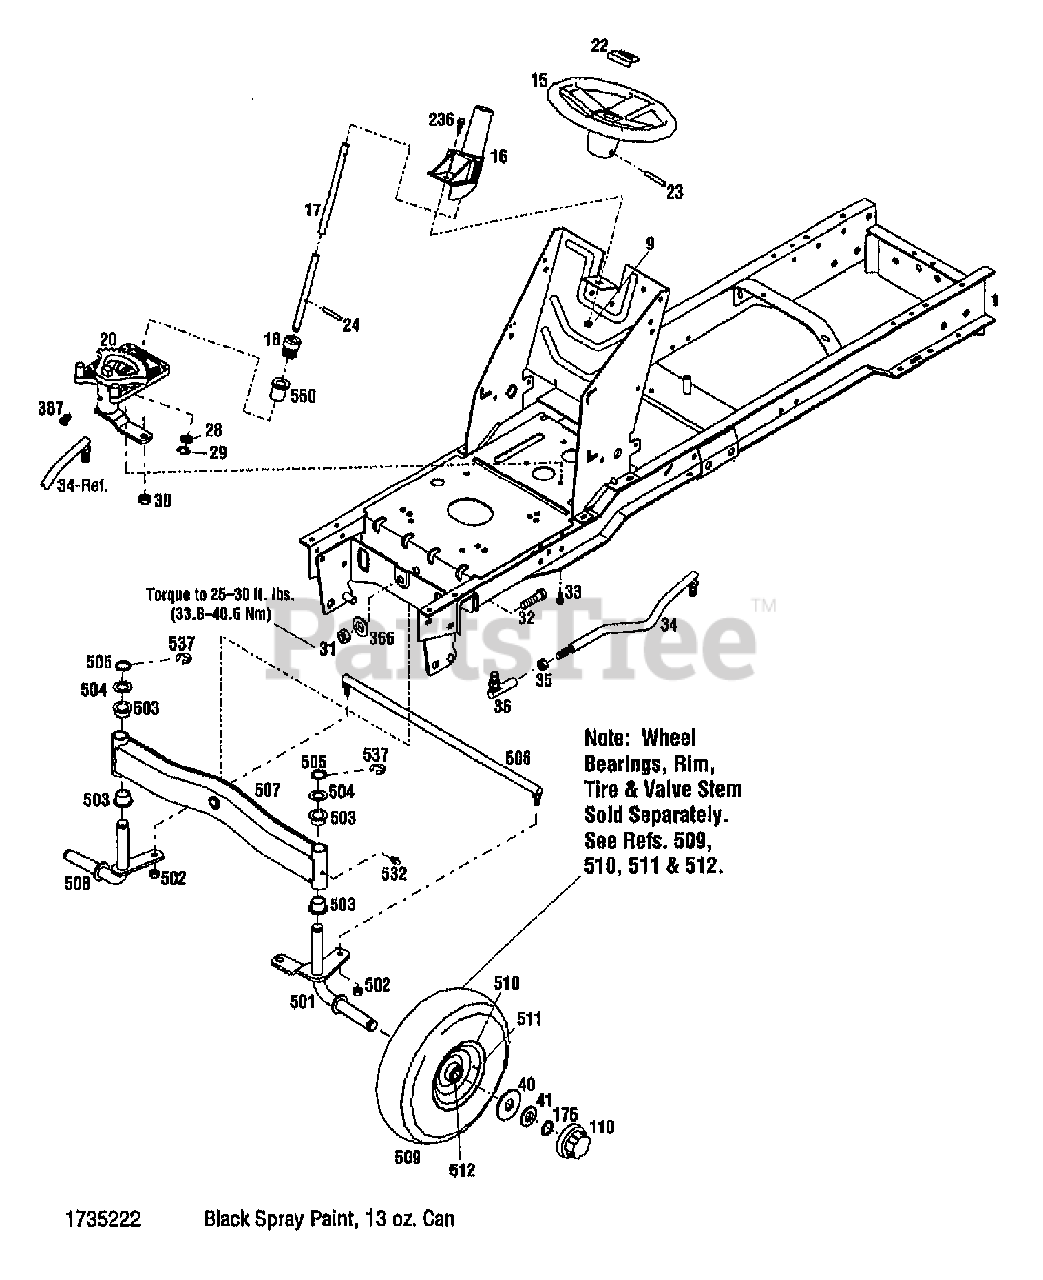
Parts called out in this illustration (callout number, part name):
9	NUT-HFLK 5/16-18 ZP
15	WHEEL-STEERING
16	SUPPORT-STEERING SHAFT
17	SHAFT-STEERING
18	GEAR-PINION
20	ASSM-STEERING GEAR
22	CAP-STEERING
23	PIN-ROLL .25X2.25
24	PIN-ROLL 1/4 X 1-1/4
28	WASHER-1.0X.64X.09
29	RING-RETAINING
30	NUT-HEX/JAM 1/2-20
31	NUT-H/LK 5/8-11
32	SCR-HH
33	SCR-HFLK 5/16-18X.75
34	LINK-DRAG
35	NUT-JAM
36	JOINT-BALL
40	WASHER-SPEC .75X2.50
41	WASHER-1.38 X.765X .06 ZP
110	CAP-HUB
236	SCR-HFLK 5/16-18X.75 ZP
501	ASSM-SPINDLE LH
502	NUT-LOCK
504	WASHER-1.25X.765X.049
505	RING-HEAVY EXT HD 1.0 ID
506	KIT-TIE ROD W/HDW
508	ASSM-SPINDLE WHEEL RH
509	TIRE 15X6.00-6RS
510	DISC WHEEL
511	STEM-VALVE
512	BEARINGS-WHEEL
532	FITTING-GREASE 1/4-28X2.00
537	RING-RET."E".577 ID
550	BEARING
